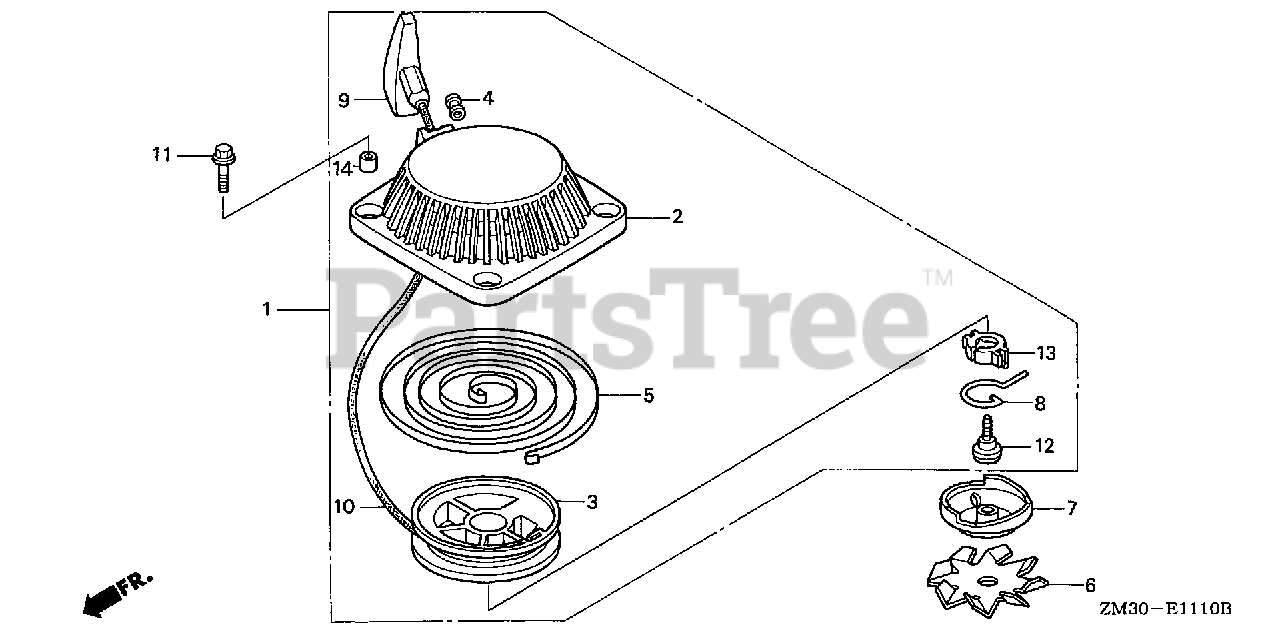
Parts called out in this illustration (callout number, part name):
1	STARTER ASSY., RECOIL *NH1* (BLACK)
2	CASE, RECOIL STARTER
3	REEL, RECOIL STARTER
4	GUIDE, ROPE
5	SPRING, RECOIL STARTER
6	FAN, RATCHET
7	PULLEY, RECOIL STARTER
9	KNOB, RECOIL STARTER
10	ROPE, RECOIL STARTER
11	BOLT, FLANGE (5X18)
12	SCREW, SETTING
